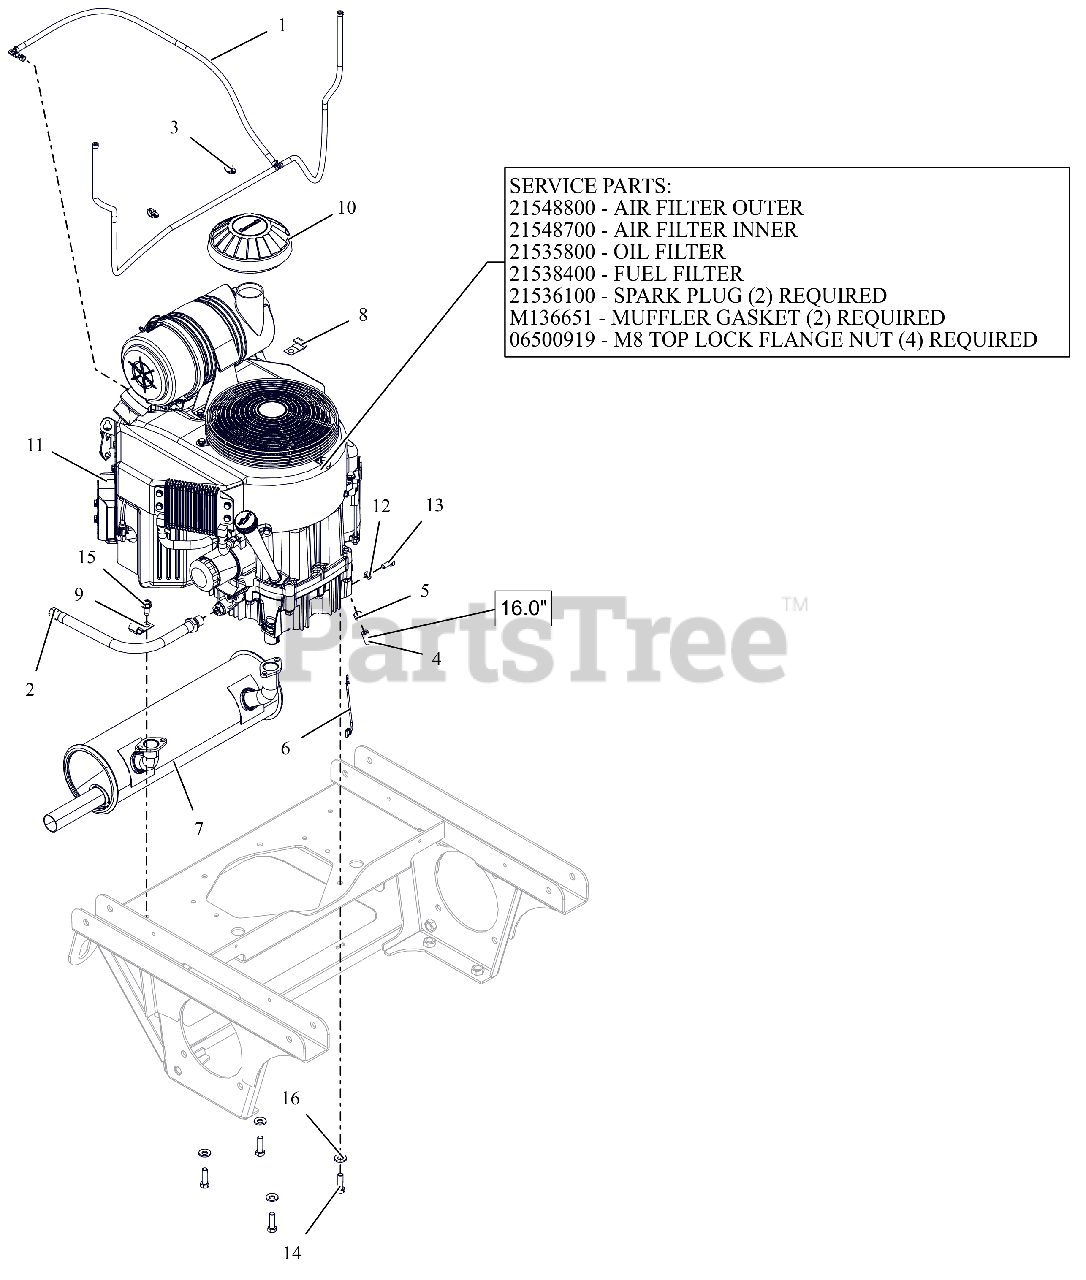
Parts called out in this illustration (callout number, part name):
1	ASM, VAPOR LINE
2	HOSE, OIL DRAIN
3	ROUTING CLIP (1/2" ID)
4	HOSE, .25 LOW-PERM BULK GAS
5	CLAMP, FUEL LINE
6	LEAD - STARTER SOLENOID
7	MUFFLER, 27-31 KAW
10	CAP, AIR CLEANER INTAKE (2")
11	ENGINE, KAWASAKI FX850
11	FILTER, OUTER
11	FILTER, INNER - KAW
11	FILTER,OIL - KAW
11	FUEL FILTER - KAWASAKI
11	PLUG, SPARK
11	GASKET, MUFFLER #
11	NUT-LK-TOP-FLG M8 ZCC
12	WSHR,LK-REG .312X.078 ZCC
13	BLT, HEX M8-1.25X20 G8.8 ZCC
14	BLT, HEX .38-16X1.25 G5 ZCC NT
15	SCR,TAP .375-16X.75 HWH TR ZCC
16	WASHER, 3/8" SPRING DISC
